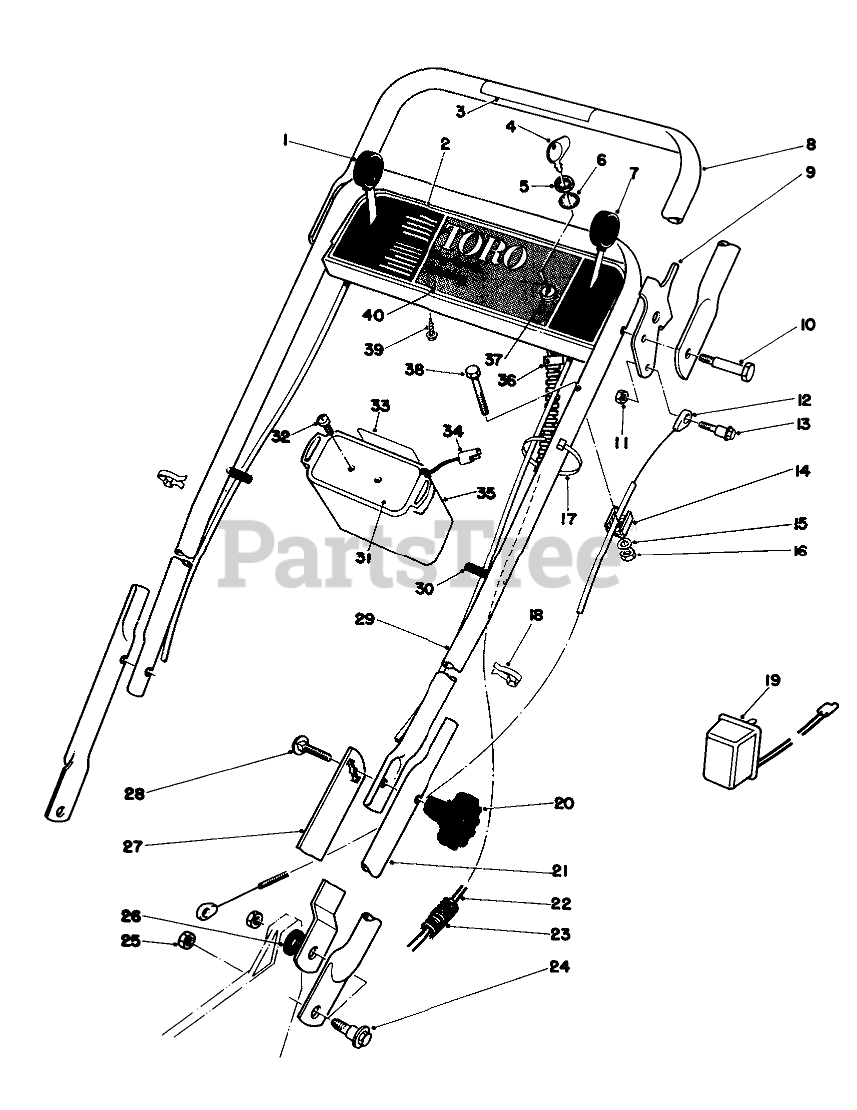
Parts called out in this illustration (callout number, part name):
1	GROUND SPEED CONTROL
2	CONTROL PLATE WA
3	Decal-Traction Control
4	Key
5	NUT-HH
6	WASHER-TOOTH, INTERNAL
7	Throttle Control
8	Demand Handle
9	Demand Handle Stop
10	BOLT-SHOULDER
11	NUT-HEX, SIDE DEFORM
12	DEMAND HANDLE CABLE
13	Shoulder Bolt
14	CLAMP-CABLE
15	WASHER-FLAT
16	NUT-LOCK, NI
17	TIE-CABLE
18	BOWDEN CLIP
19	Charger
21	LOWER HANDLE
22	WIRE HARNESS
23	Cover-Wiring Harness
24	SCREW-SHOULDER
25	Nut
26	SPACER
27	Handle Latch L.H.
28	SCREW-CARR
29	Upper Handle
30	CAP-VINYL
31	BATTERY COVER
32	10-190X1/2 PAN HD SCR
33	Decal
34	Plug & Wire
35	Battery Case
36	RING FITTING
37	Starter Switch (Incl. Ref. #4-6)
38	SCREW-HH
39	SCREW-HWHTF
40	Decal Lectric
